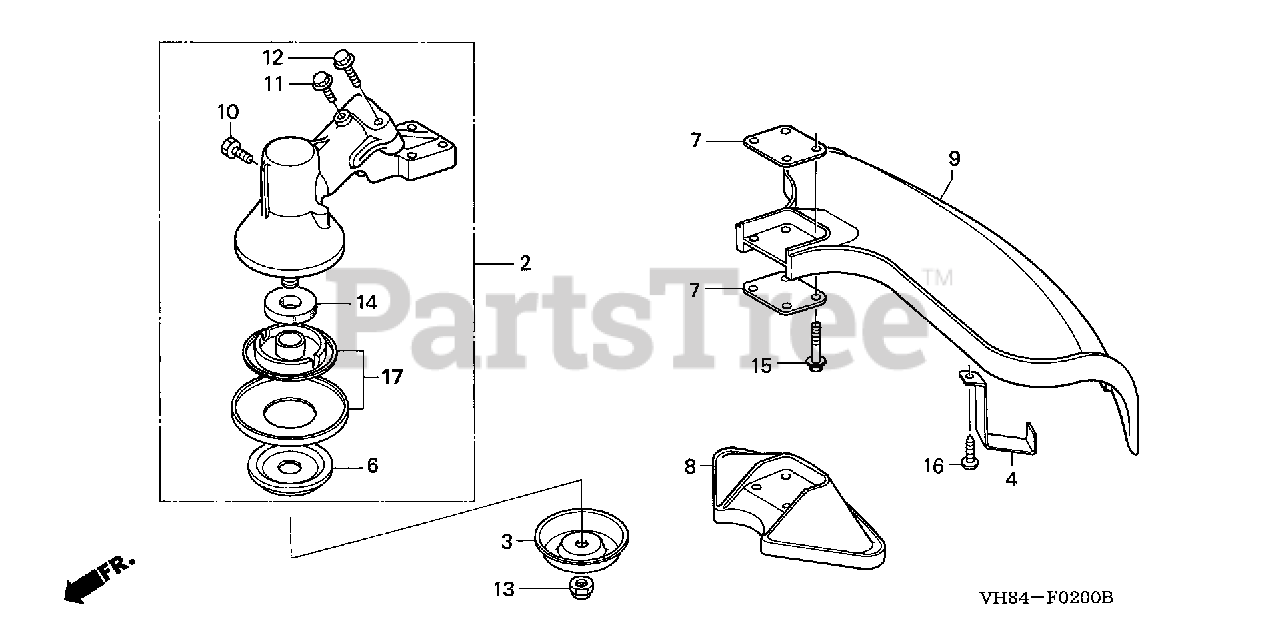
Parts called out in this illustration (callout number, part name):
2	CASE ASSY., GEAR
4	PLATE, NYLON CUTTING
6	HOLDER B, BLADE
7	SPACER, DEFLECTOR
9	DEFLECTOR, GRASS
10	BOLT, HEX. (8X10)
11	BOLT-WASHER (5X12)
12	BOLT-WASHER (5X25)
15	BOLT-WASHER (5X28)
16	SCREW, TAPPING (5X12) (PO)
17	HOLDER, BLADE
